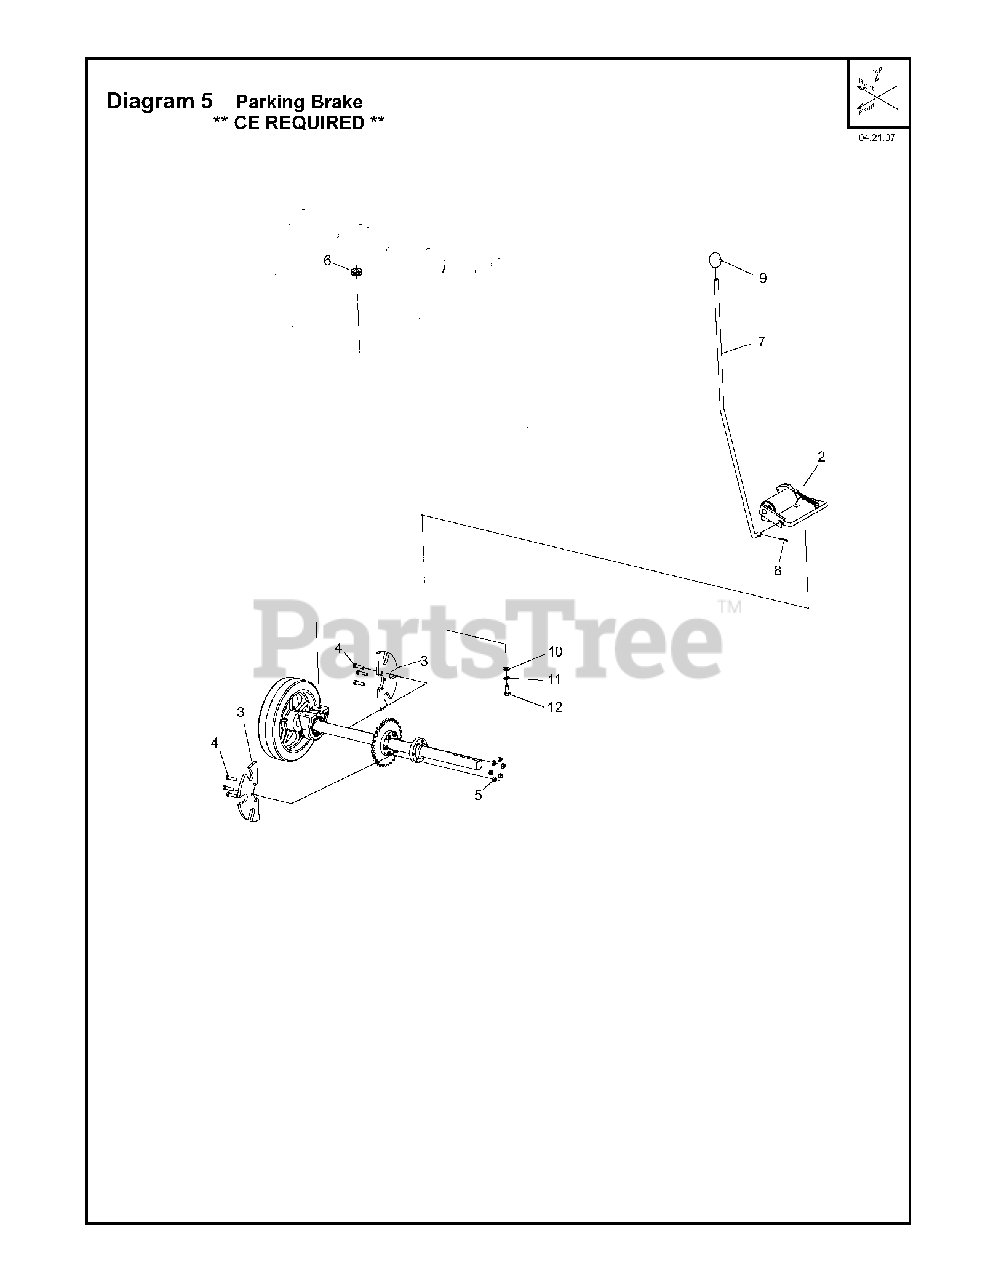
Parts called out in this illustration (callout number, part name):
2	BRAKE ASSEMBLY. PRO 35
3	BRAKE DISC - PAINTED BLACK
4	HHCS. M6 x 1.0 x 25 DIN931 Z/P
5	LOCKNUT. FIBER M6 DIN 985
7	CONTROL ROD PRO 35 Z/P
8	PIN. COTTER HAIR
10	WASHER
11	LOCKWASHER. SPLIT .3125 (M8)
12	HHCS. M8 x 1.25 x 20 DIN933 ZP
